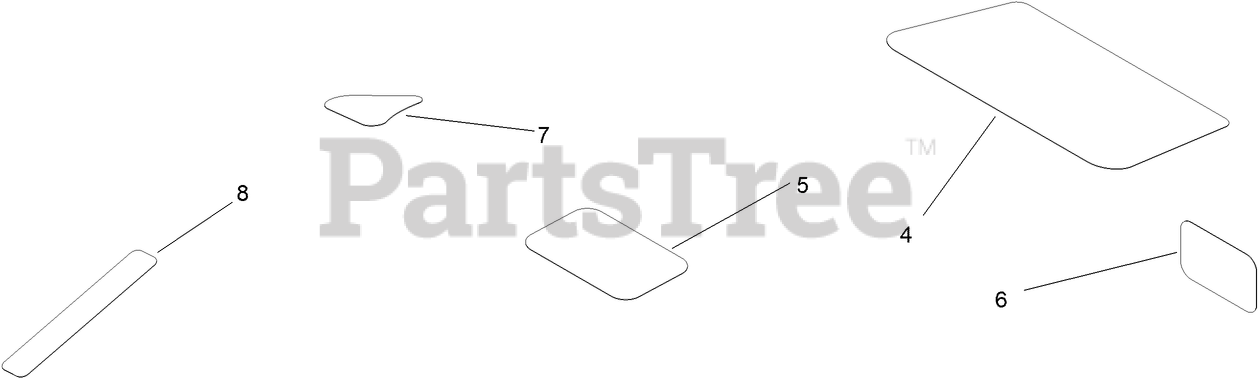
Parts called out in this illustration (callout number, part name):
4	DECAL-ENGINE
6	PLACARD-INTAKE
7	DECAL-DRAIN, OIL
8	DECAL-SHUTDOWN
